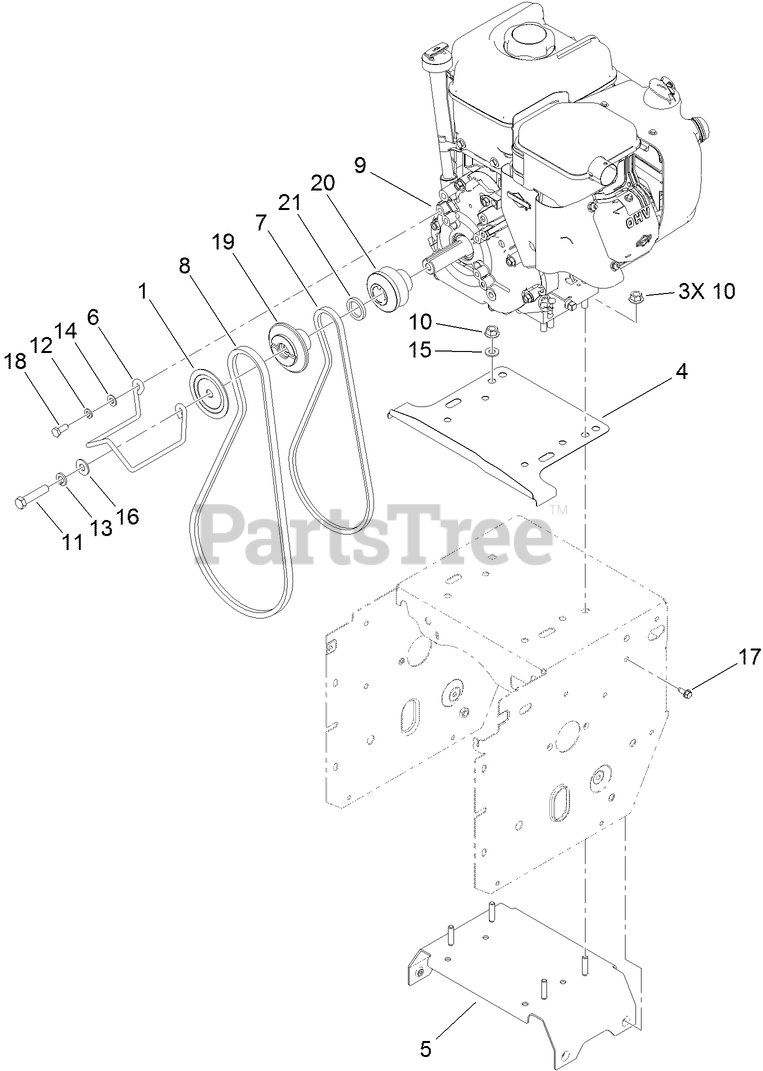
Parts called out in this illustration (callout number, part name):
1	SHEAVE-HALF, IMPELLER
4	SHIELD-DRIVE
5	FRAME BRACE ASM
6	GUIDE-BELT
7	V BELT-TRACTION
8	BELT-V
10	NUT-HF
11	SCREW-HH
12	WASHER-LOCK
13	WASHER-LOCK
14	WASHER-PLAIN
15	WASHER-FLAT
16	WASHER-FLAT
17	SCREW-HWH
18	SCREW-HH
19	PULLEY-ENGINE, IMPELLER
20	PULLEY-TRACTION
21	SPACER-HARDENED
